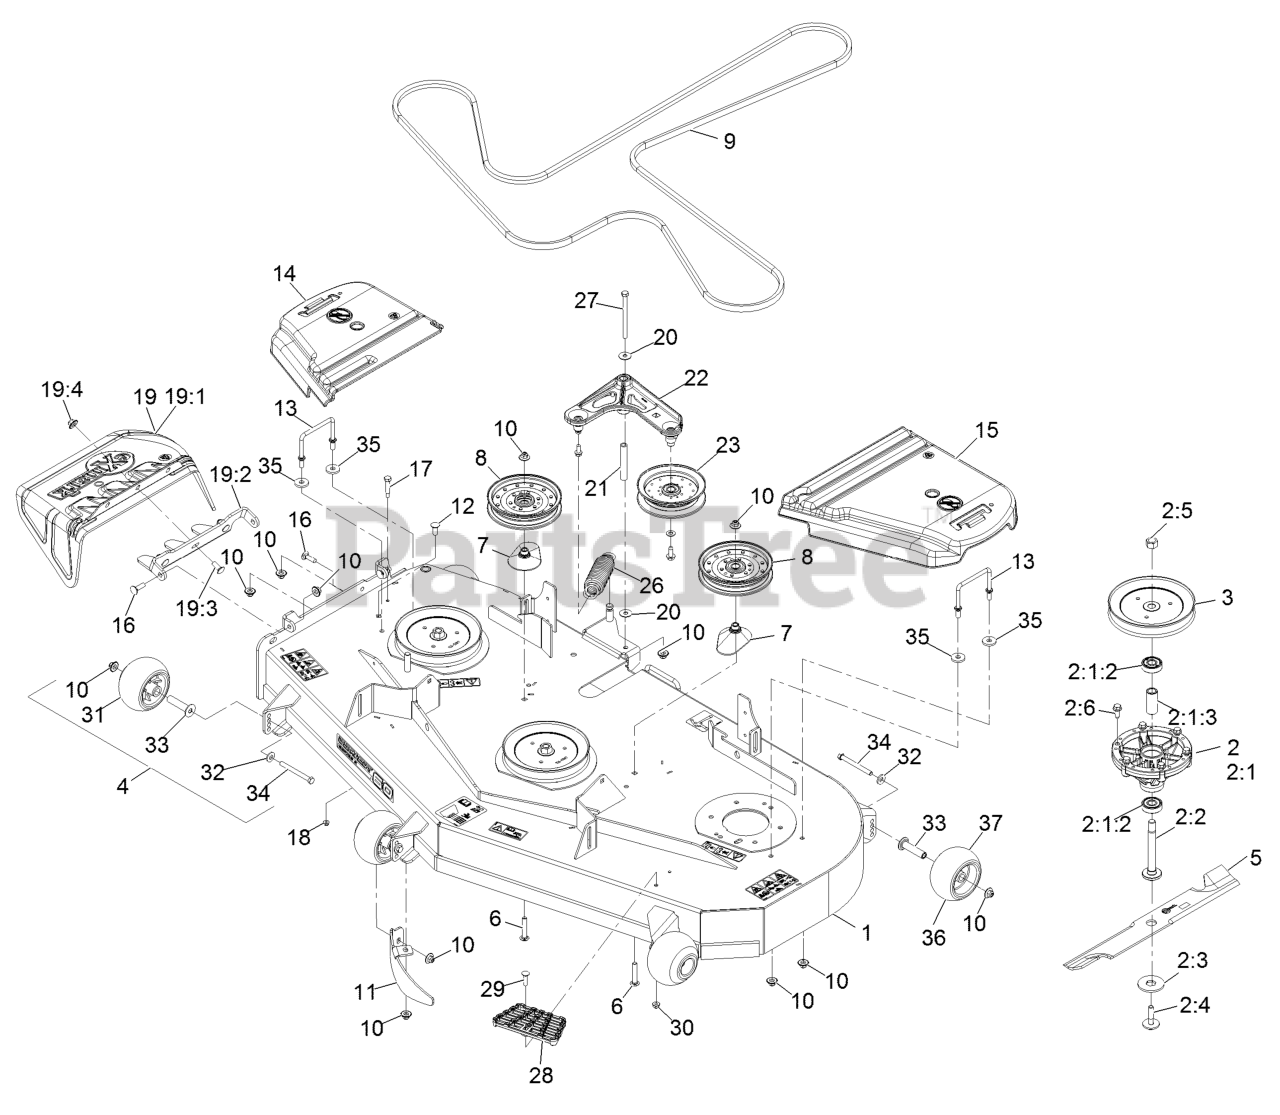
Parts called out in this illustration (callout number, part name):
1	ASM-DECK W/DECALS 603
2	ASM, CUTTER HOUSING COMPL
2:1	ASM-CUTTER HOUSING
2:1:2	BEARING
2:1:3	SPACER-BEARING
2:2	SPINDLE-HEX PILOT
2:3	WASHER-HEX BLADE DRIVE
2:4	BOLT-BLADE, SEM
2:5	NUT-HEX
2:6	SCREW-FORMING, THREAD
3	SHEAVE,BLADE DRIVE 7.25
4	KIT, ANTI-SCALP ROLLER
5	Blade-Extreme 2, 20.50"
6	BOLT-CARR, SHORT NECK
7	SPACER-PULLEY
9	BELT-V
10	Nut-Nyloc 3/8-16 Flg
11	DOGLEG-603
12	SCREW-CARR
13	WIREFORM-COVER
14	COVER-BELT, RH
15	COVER-BELT, LH
16	BOLT-CARR
17	BOLT-SHOULDER
19	ASM,DISCHARGE CHUTE
19:1	CHUTE,DISCHARGE
19:2	BRACKET,DISCHARGE CHUTE
19:3	SCREW-CARR
19:4	Nut-Nyloc 3/8-16 Flg
21	BUSHING
22	IDLER ARM ASM
26	SPRING-EXTENSION
27	SCREW-HH
28	STEP-DECK
29	Bolt-Carriage 5/16-18 X 1 1/4
30	NUT-HF, NI
31	ROLLER-SCALP, ANTI
32	WASHER-BELLEVILLE
33	AXLE, ROLLER
34	SCREW-HH 3/8-16 X 3 3/4 GR 8
36	KIT-ANTISCALP ROLLER
37	ROLLER-SCALP, ANTI
